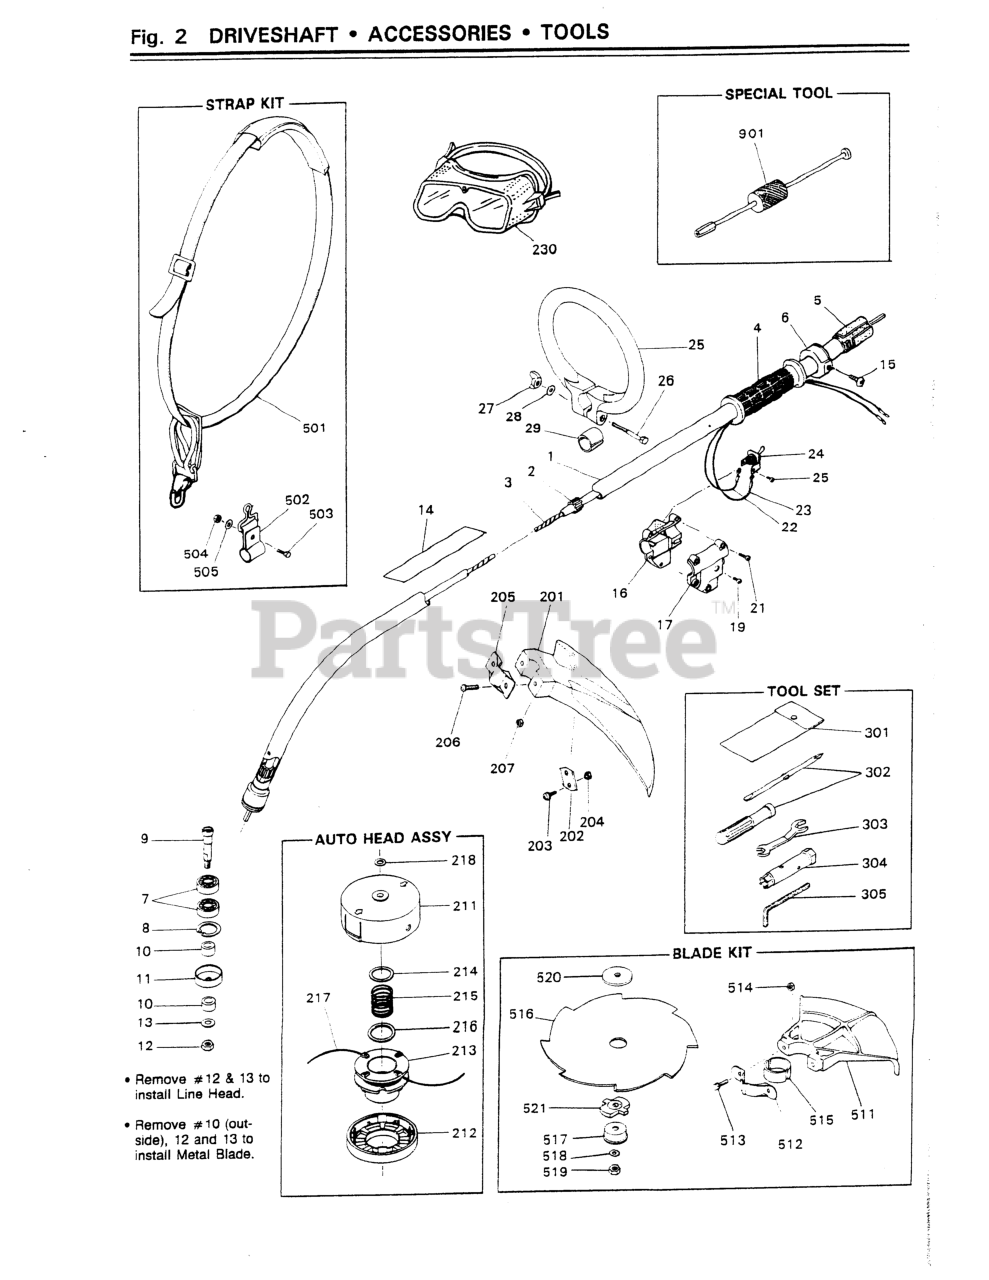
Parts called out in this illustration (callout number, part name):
1	PIPE ASSEMBLY
2	PIPE ASSEMBLY
3	SHAFT, FLEX (NO LONGER AVAIL)
8	RING, SNAP, M32 x 1.2
9	SHAFT (NO LONGER AVAILABLE)
10	COLLAR (NO LONGER AVAILABLE)
11	COVER (NO LONGER AVAILABLE)
12	NUT, M8 x 6
13	WASHER (NO LONGER AVAILABLE)
14	NAME PLATE
15	SCREW, M5 X 10
16	CASE (NO LONGER AVAILABLE)
17	CASE-L (NO LONGER AVAILABLE)
19	SCREW, M5 X 6 (USE 0260-20508)
21	SCREW, HOUSING
22	CORD (A) (NO LONGER AVAIL)
25	SCREW, M4 X 5
26	BOLT, M6 X 50
27	NUT, WING
28	WASHER, M6 X 16
203	SCREW, M4 X 12
205	CLAMP (NO LONGER AVAILABLE)
206	SCREW, M6 X 20
207	NUT, M6 X 5
213	HOLDER, CORD
214	PLATE, LARGE
216	PLATE, SMALL
218	WASHER, M8 x 16
302	SCREWDRIVER
303	SPANNER, 8 X 10 (RPLS 2540- )
305	WRENCH (TOOL)
504	NUT, M6 X 5
505	WASHER, M6 X 15
511	COVER, BLADE
513	BOLT, M6 x 25
514	NUT, M6 X 5
516	BLADE, EDDY-SAW
518	WASHER, M8 x 8
519	NUT, M8 x 6
520	HOLDER (A) (RPLS -13251)
521	HOLDER (B) (NO LONGER AVAIL)
NI	LEVER, THROTTLE (NLA)
NI	SPRING (NO LONGER AVAILABLE)
